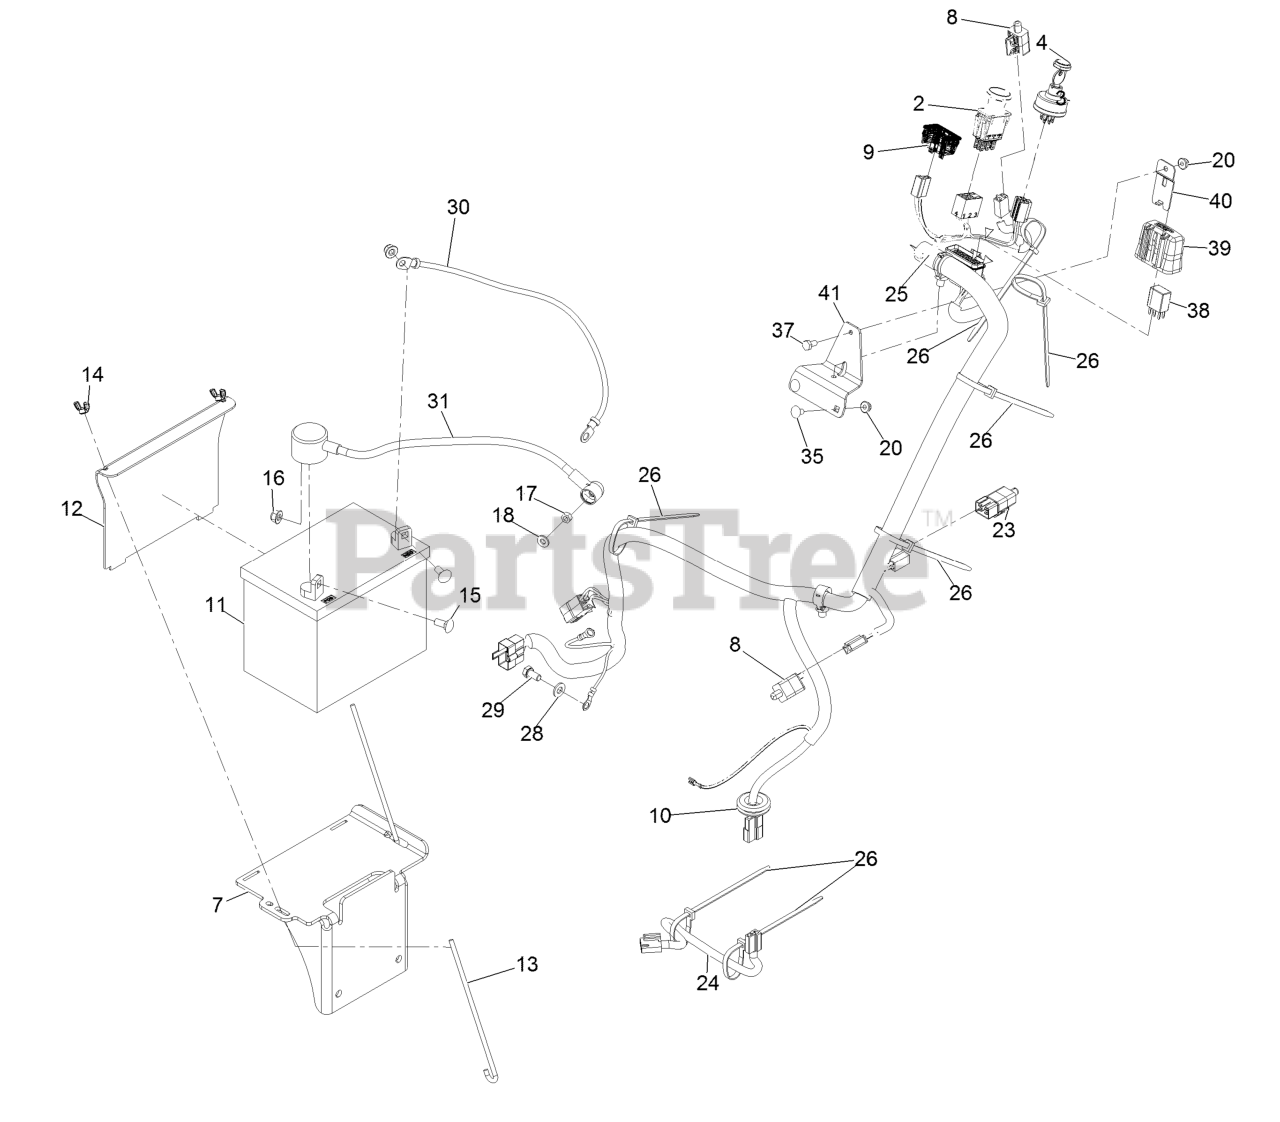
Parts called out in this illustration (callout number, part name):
2	Switch-PTO
3	Switch, Key Start
4	Nut-Ignition
7	Weld, Battery Mount
9	Hour Meter
10	Grommet
11	Battery (300 CCA, Wet)
12	Bracket, Battery Hold Down
13	Bolt-Holddown
14	Wingnut-Nyloc 1/4-20
15	Bolt-Carriage 5/16-18 X 3/4
16	Nut-Nyloc 5/16-18 Flg
17	Nut-Hex 1/4-20
18	Washer-1/4 SAE
23	Switch, 2 Pole
24	Harness-Clutch Pigtail
25	Harness-Wiring
26	Tie-Cable 7 15/16 (Large)
29	Screw-HH M8-1.25 X 16Mm
30	Cable-Battery, Negative
31	Cable, Battery +
35	Screw-CARR
37	Screw-HH
38	Relay-Micro 280, Spdt
39	Cover-Block, Fuse
40	Clip-Mounting
41	Bracket-Mounting, Fuseblock
